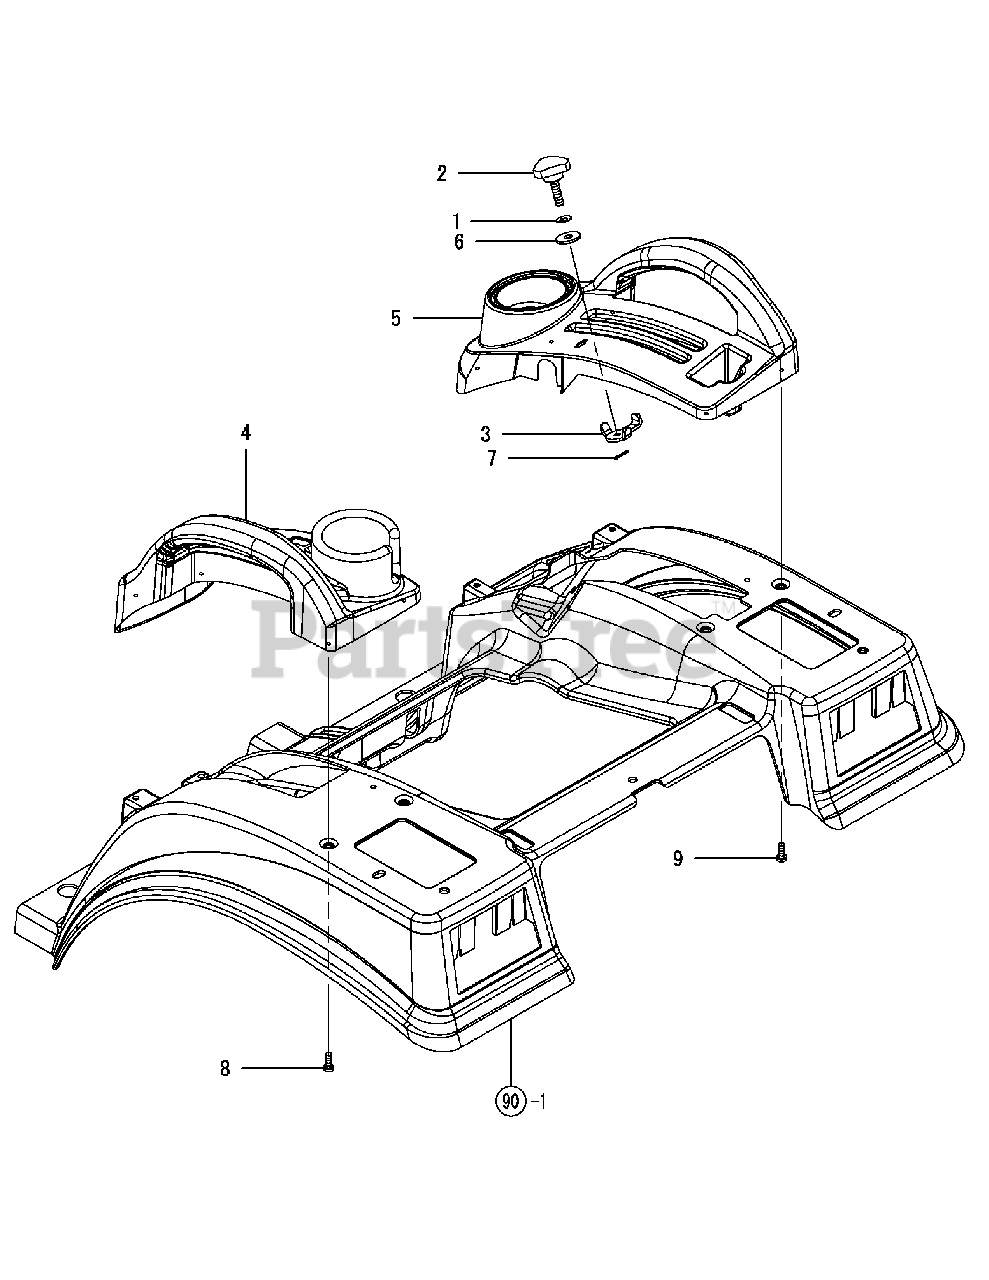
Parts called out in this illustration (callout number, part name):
1	SPRING, CONICAL
2	KNOB, HYD.CONTROL
3	STOPPER, HYD.CONTROL
4	GUIDE M ASY LEVER L
5	GUIDE, LEVER R
7	COTTER PIN 2.0X16
